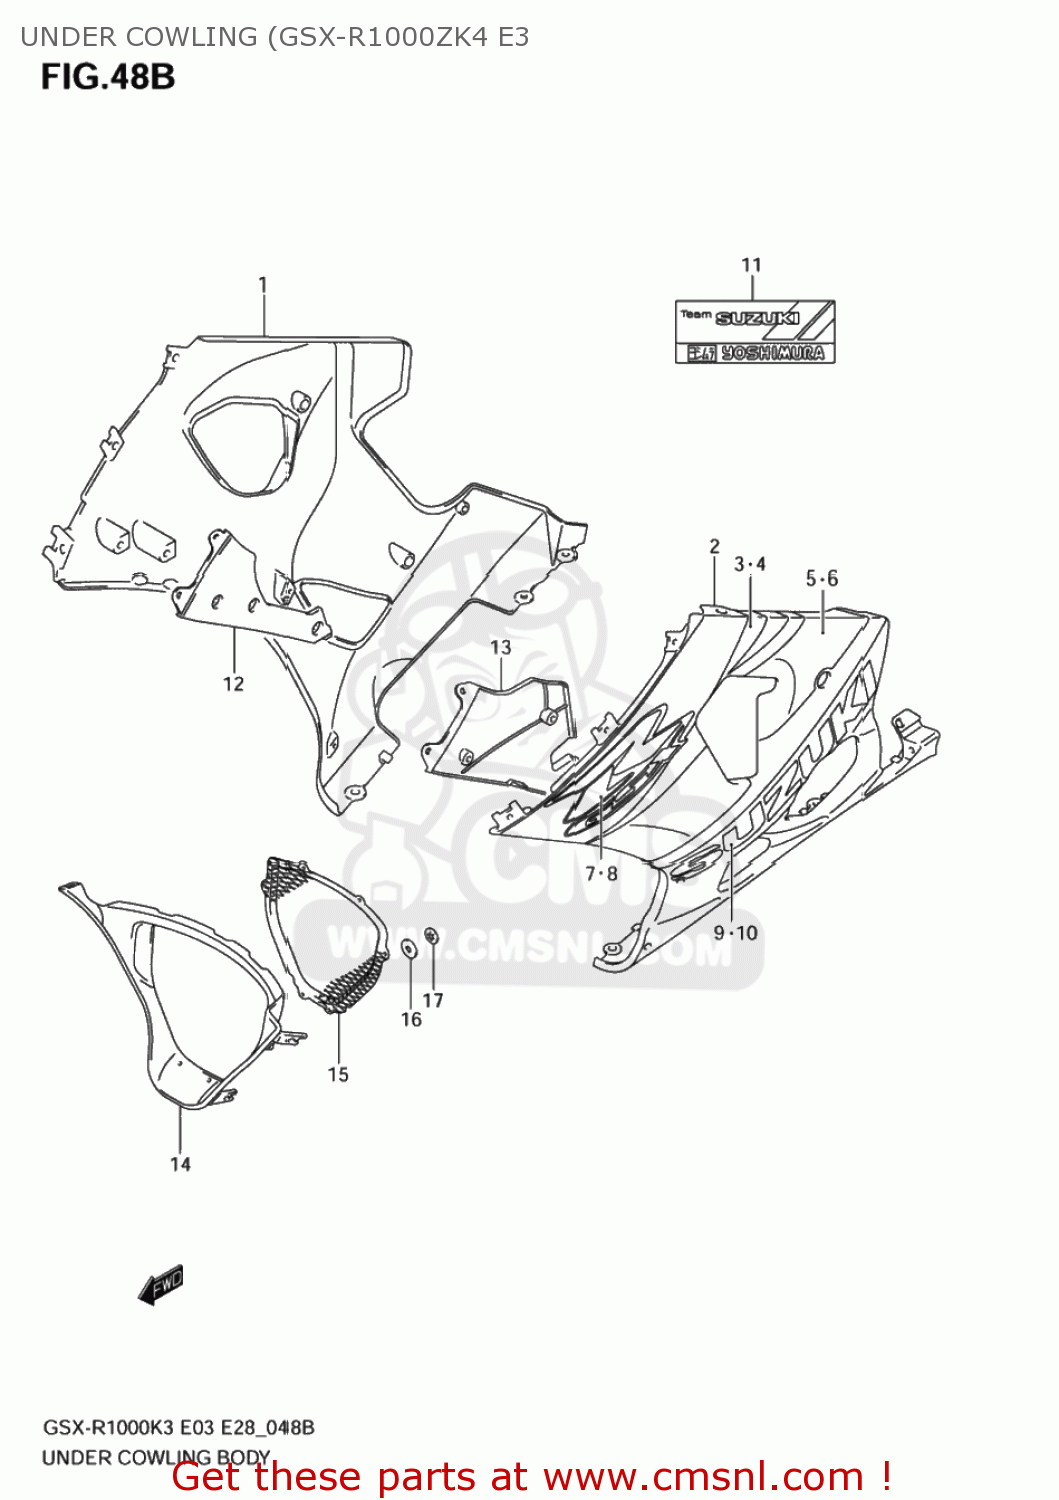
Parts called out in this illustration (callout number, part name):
1	COWLING ASSY,UNDER,R
2	COWLING ASSY,UNDER,L
3	TAPE,COWL UPR,R
4	TAPE,COWL UPR,L
5	TAPE SET,COWL MIDDLE,R
6	TAPE SET,COWL MIDDLE,L
7	EMBLEM,GSXR,R
8	EMBLEM,GSXR,L
9	EMBLEM,SUZUKI,R
10	EMBLEM,SUZUKI,L
11	EMBLEM,TEAM-SUZUKI
12	COWLING,UNDER INNER,R
13	COWLING,UNDER INNER,L
14	COWLING,UNDER CTR
15	COWLING,UNDER CTR
16	CUSHION
17	NUT
